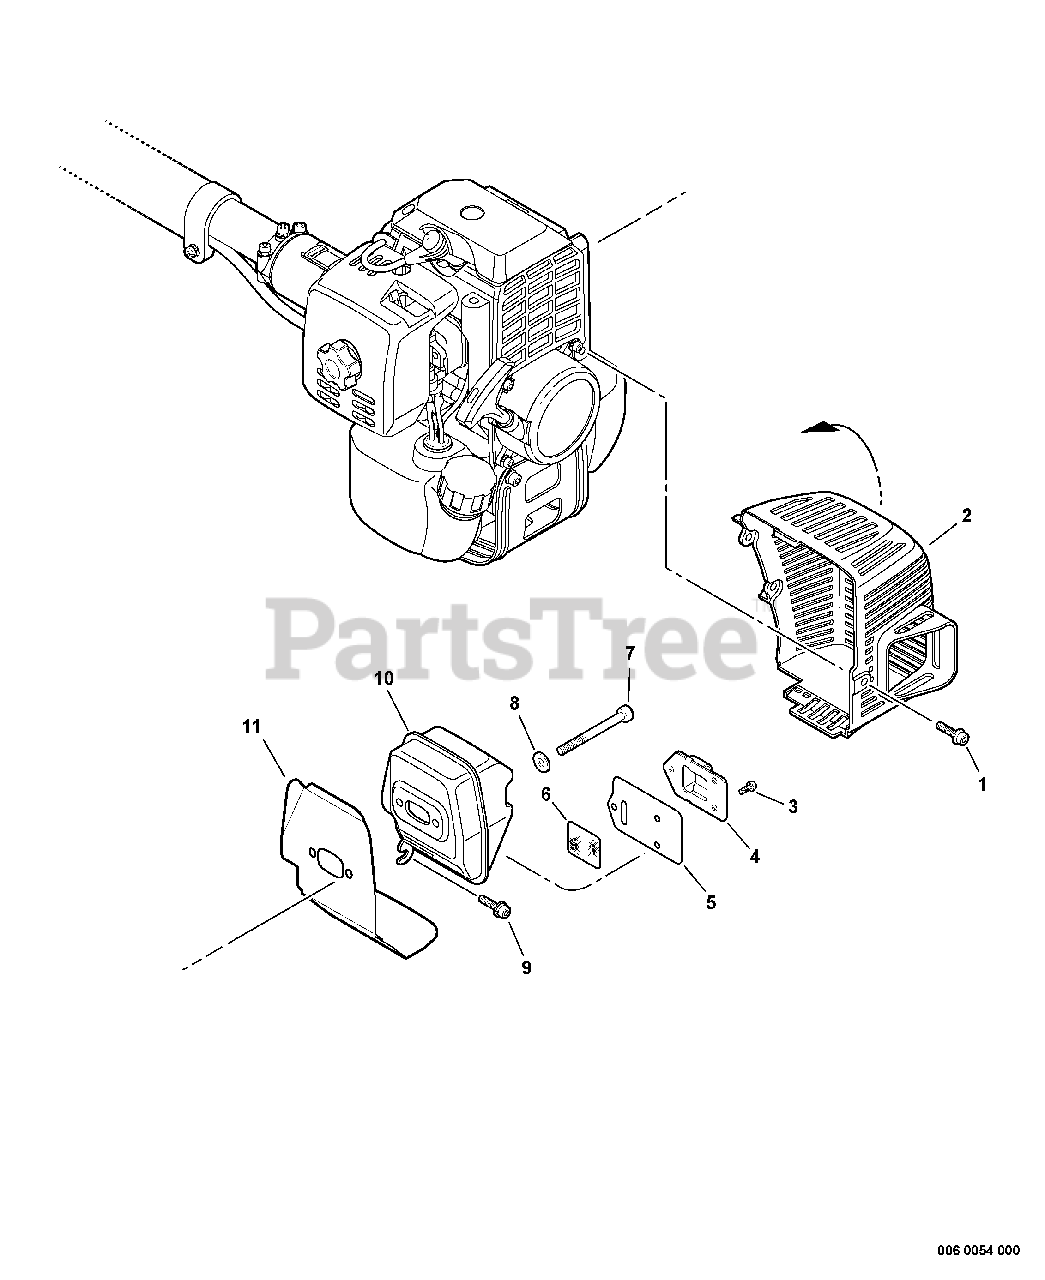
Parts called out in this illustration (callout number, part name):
1	SCREW - 5X14
2	COVER, EXHAUST
3	SCREW - 4X10
4	GUIDE, EXHAUST
5	GASKET, EXHAUST
6	SCREEN, SPARK ARRESTOR
7	SCREW - 5X60
8	WASHER - 5
9	SCREW - 5X12
10	MUFFLER
11	SHIELD, EXHAUST
